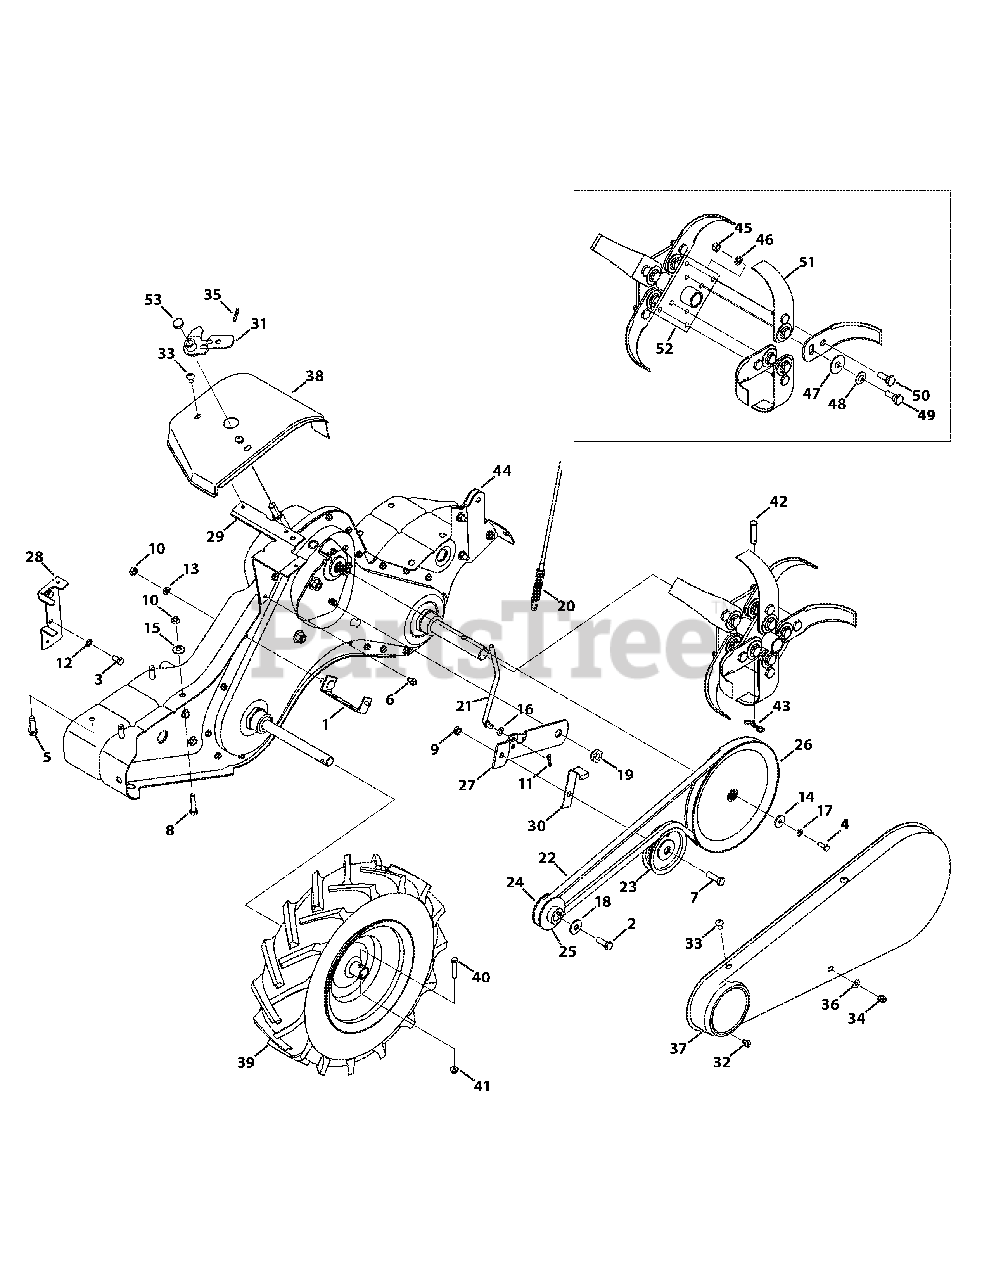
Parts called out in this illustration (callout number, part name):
1	Belt Cover Bracket Assembly
2	Hex Head Screw, 3/8-24 x 1.00
3	Hex Head Screw, 5/16-24 x .625
4	Hex Head Screw, 1/4-28 x .75
5	Screw, 3/8-16 x 1.250
6	Screw, 1/4-20 x 0.500
7	Hex Head Screw, 3/8-16 x 1.25
8	Hex Head Screw, 5/16-18 x 1.50
9	Jamlock Nut, 3/8-16
10	Hex Nut, 5/16-18
11	Cotter Pin, .072 DIA. x 1.13 LG
12	Washer, Lock, 5/16
13	Washer, Lock, 5/16
14	Washer, Flat, .265 x .938 x .120
15	Washer, Bell, .340 x .872 x .060
16	Washer, Spring, .317 x .625 x .020
17	Washer, Lock, 1/4
18	Washer, Bell, .396 x 1.140 x .095
19	Shoulder Nut, 7/16-20
20	Clutch Cable
21	Idler Pulley Rod
22	Belt, 4L x 58.16 LG
23	Flat Idler Pulley w/ Flanges, 3.75 O.D.
24	Engine Pulley, Inner Half
25	Engine Pulley, Outer Half
26	Input Pulley, 4L x 8.594
27	Idler Pulley Bracket
28	Belt Keeper Bracket, B&S 6.5 HP
29	Shift Cover Bracket
30	Idler Belt Keeper
31	Shift Crank Assembly
32	Screw, 1/4-20:0.375
33	Screw, 1/4-14:0.625
34	Lock Nut, Cap, 1/4-28
35	Spiral Pin, 3/16 x 1.00
36	Washer, Flat, .271x .630 x .065
37	Belt Cover - Gray
37	Belt Cover - Black Jack
37	Belt Cover - Red
38	Shift Cover - Red
38	Shift Cover - Black
39	Wheel, 16 x 4.6 x 8
39	Wheel, 14 x 4.5 x 6
40	Hex Head Screw, 1/4-20 x 1.50
41	Flangelock Nut, 1/4-20
42	Clevis Pin, .375 x 1.75
43	Cotter Pin, Bow-Tie
44	Complete Gear Case Assembly
45	Hexlock Nut, 3/8-24
46	Washer, Lock, 3/8
47	Washer, Flat, .51 x 1.5 x 0.07
48	Washer, Bell, .525 x 1.00 x .050
49	Screw, Shoulder, 3/8-24 x 1/2 x .325
50	Screw, Shoulder, 3/8-24 x 1/2 x .180
51	Articulating Tine
52	Tine Adaptor Assembly
52	Tine Assembly
